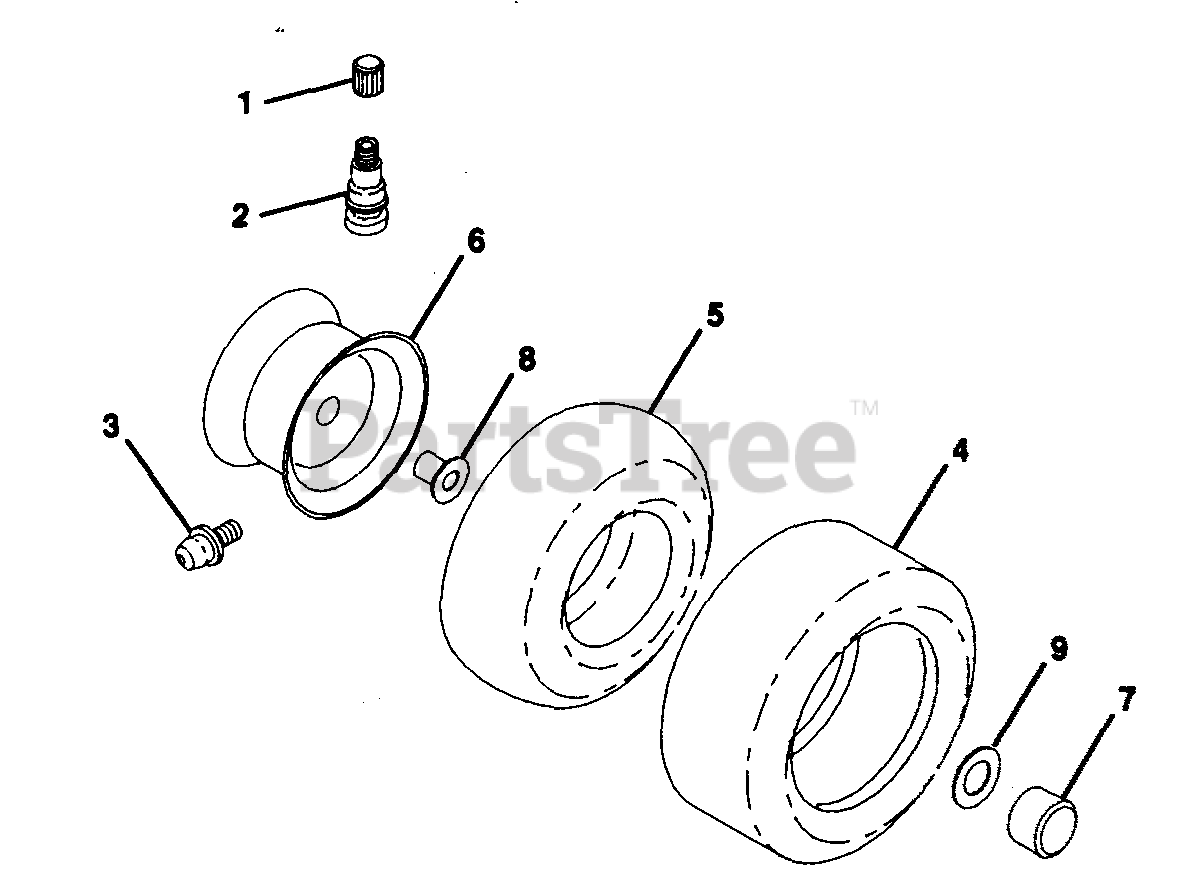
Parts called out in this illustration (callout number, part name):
1	Cap; Valve, Tire
2	Stem, Valve
3	Fittin~ Grease
4	Tire, ront
5	Tube, Front Tire
6	im Assembly, Front
8	Bearing, Flange
9	Washer 25/32 x 1-5/8 x 16 Gauge
